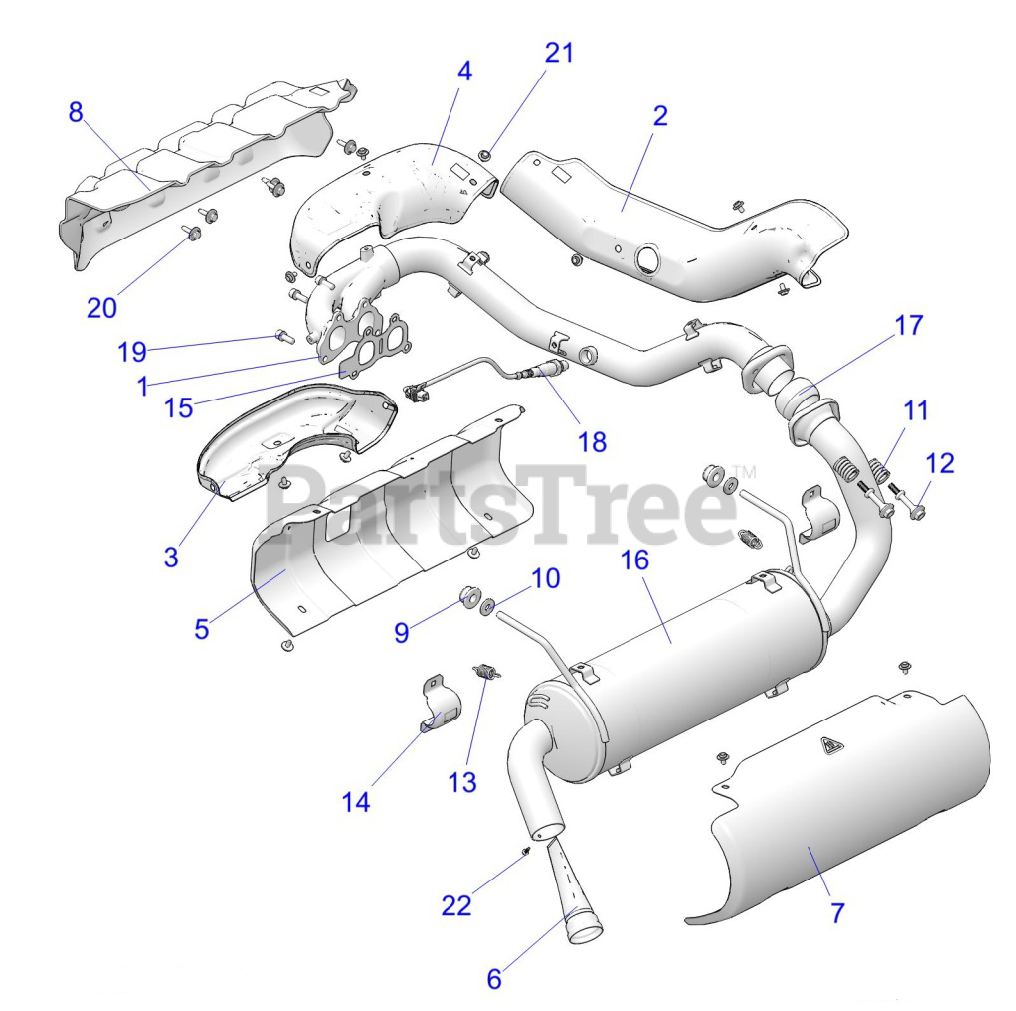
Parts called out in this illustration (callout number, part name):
1	ASM-HEADPIPE
2	SHIELD-HEAT-HEADPIPE-INNER
3	SHEILD-HEAT-HEADPIPE-FRONT-LWR
4	SHIELD-HEAT-HEADPIPE-FRONT-UPR
5	SHIELD-HEAT-SILENCER-INNER
6	WELD-SPARK ARRESTOR
7	SHIELD-HEAT-SILENCER-OUTER
8	SHIELD-HEAT,CLOSEOFF
9	ISOLATOR-EXHAUST,HANGER,HD
10	WASHER- .406X1.00X.125 FL
11	SPRING, SPHERICAL, EXHAUST
12	STUD-SPHERICAL-EXHAUST
13	SPRING-EXHAUST SS SHOTPEENED
14	SHIELD-BUSHING-SWAY BAR
15	GASKET-EXHAUST SEAL
16	ASM-SILENCER-RGR
17	GASKET-DOUBLE SPHERICAL-2"
18	SENSOR-LAMBDA-LSF 4.2
19	SCR-M8X1.25X22-HX/SO
20	SCR-HXFL-M6X1.0X25 8.8 ZPB SEM
21	SCR-HHSEMS-M6X1.0X10 A286-LOCK
22	SCR-HXFL-M6X1.0X10 8.8
